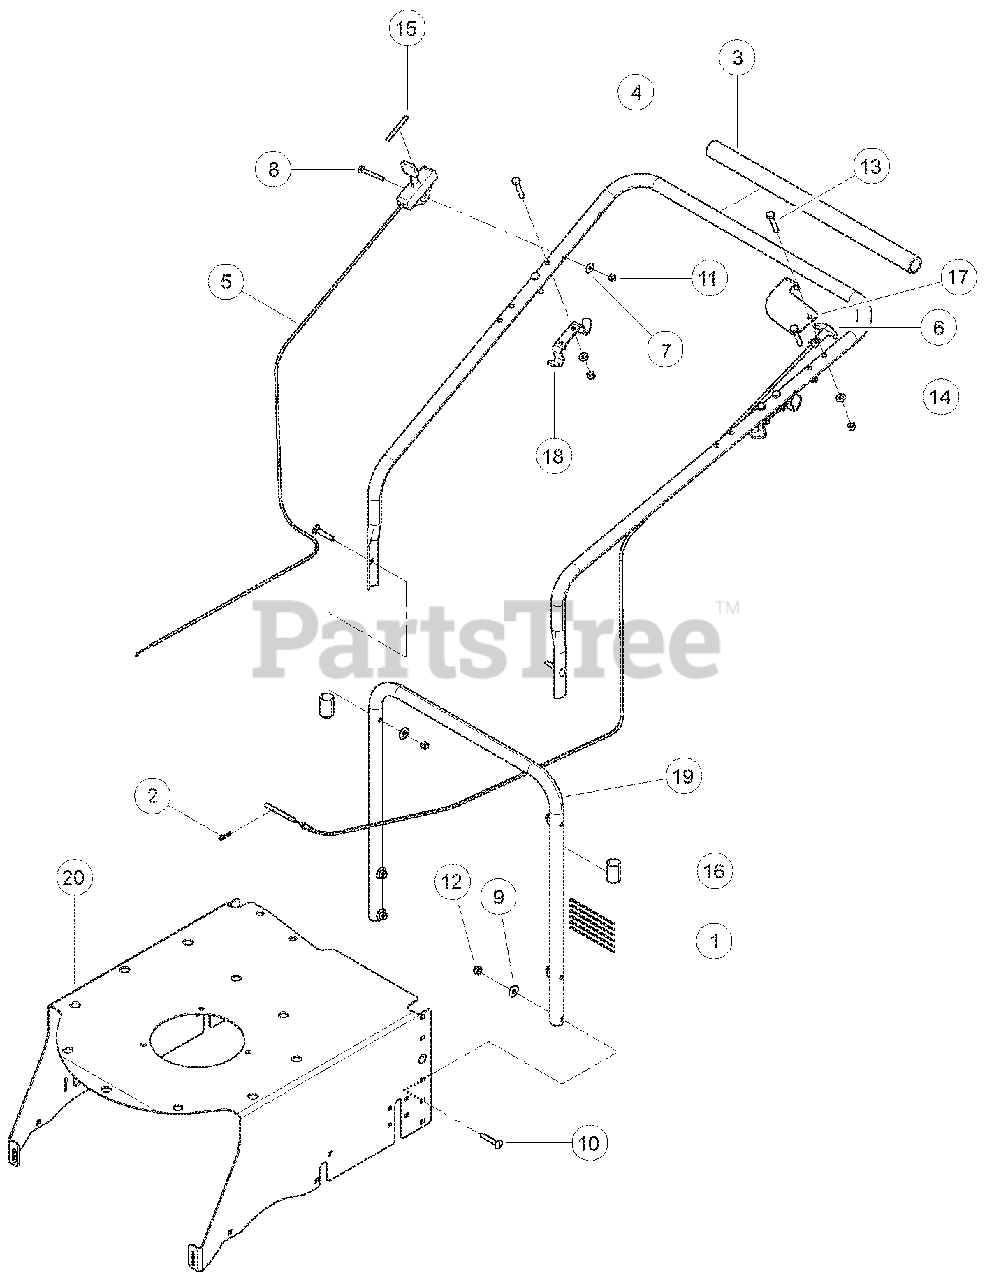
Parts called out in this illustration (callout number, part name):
1	STRAP, 4-1/2 BLACK TIE
2	CLIP, HAIRPIN ZP
3	PAD, FOAM HANDLEBAR
4	HANDLEBAR, BEARVAC UPPER
5	CONTROL, THROTTLE
6	CONTROL, HEIGHT ADJUSTMENT
7	WASHER, 1/4 FLAT ZP
8	BOLT, 1/4 X 2 HEX HD GR5 ZP
9	WASHER, 5/16 FLAT ZP
10	BOLT, 5/16 X 1-3/4 CRG GR5 ZP
11	NUT, 1/4 NE NYLOCK ZP
12	NUT, 5/16 NE NYLOCK ZP
13	BOLT, 5/16-18 X 1-3/4 HCS GR5 ZP
14	WASHER, 5/16 SAE FLAT ZP
15	DECAL, THROTTLE
16	PLASTIC CAP 7/8
17	BRACKET, BEARVAC CABLE MOUNT
18	BRACKET, BAG HANGER
19	HANDLEBAR, LOWER BEARVAC
20	SUPPORT, BEARVAC FRAME
